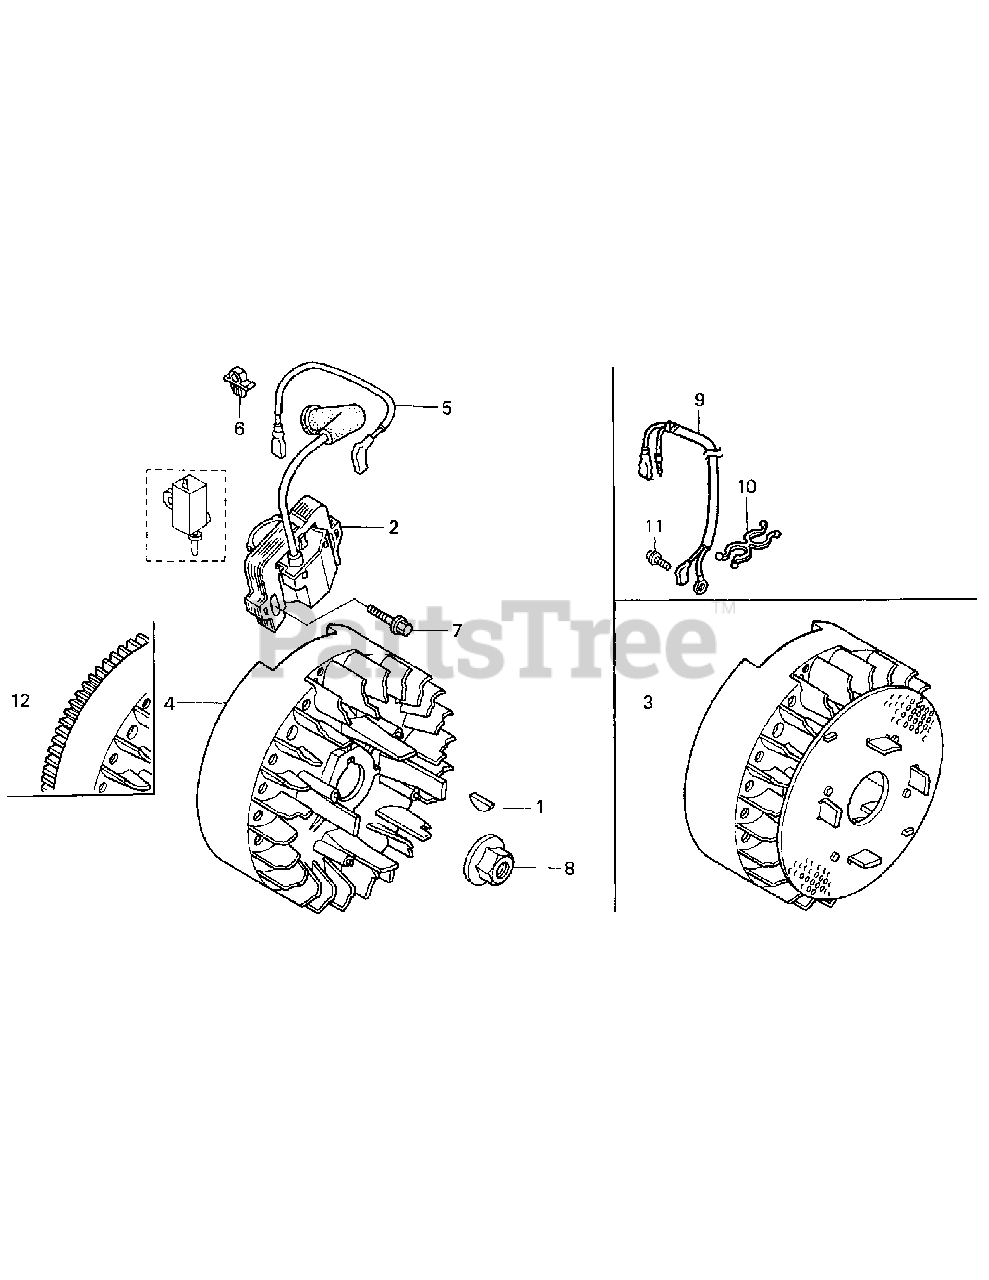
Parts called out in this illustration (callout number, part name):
1	KEY, SPECIAL WOODRUFF (25X18)
2	COIL ASSY., IGNITION
5	WIRE, STOP SWITCH
6	HOLDER, STOP SWITCH WIRE
7	BOLT, FLANGE (6X20) (CT200)
8	NUT, SPECIAL (14MM)
